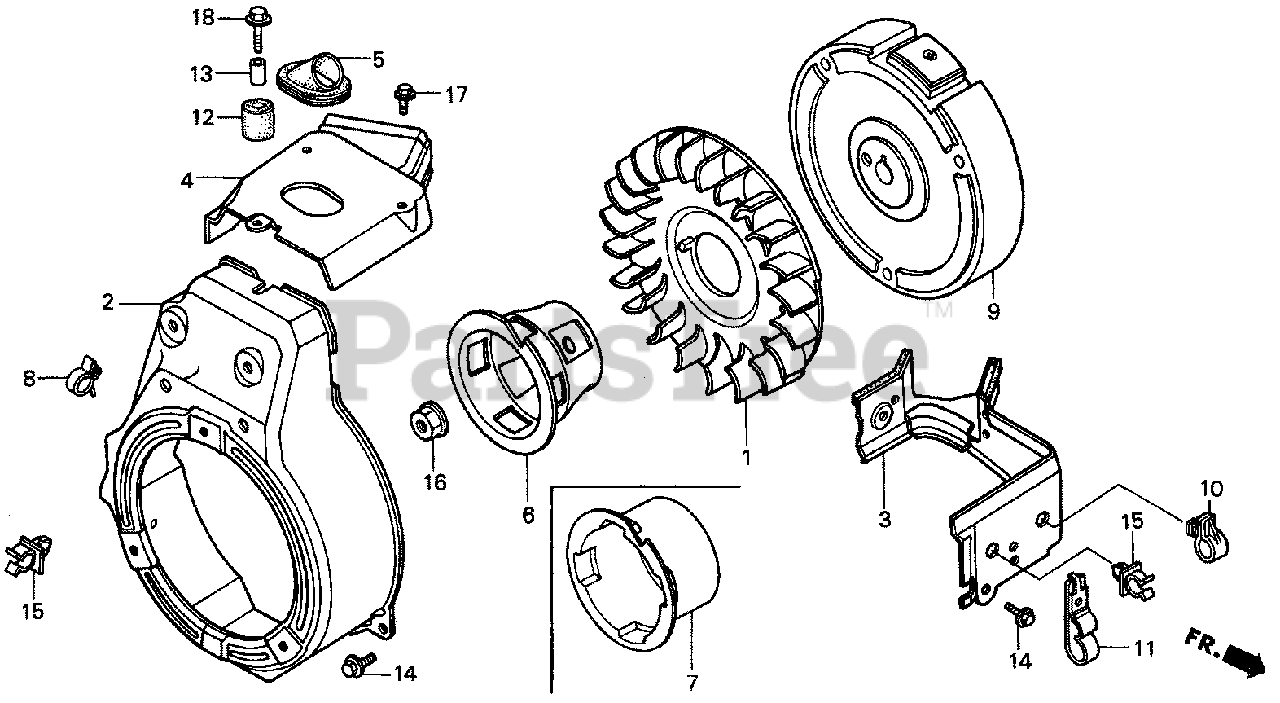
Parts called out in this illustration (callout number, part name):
1	FAN, COOLING
2	COVER, FAN
4	COVER, TOP
5	COVER, PLUG
6	PULLEY, STARTER
7	PULLEY, STARTER
8	CLIP, IGNITION WIRE (8MM)
10	CLIP, RECEIVER PIPE
11	HOLDER, CORD
12	RUBBER, STOPPER
13	COLLAR, TAILLIGHT MOUNTING
14	BOLT, FLANGE (6X12) (CT200)
15	CLIP, ROD HOLDER
16	NUT, FLANGE (12MM)
17	BOLT, FLANGE (6X12)
18	BOLT, FLANGE (6X20)
